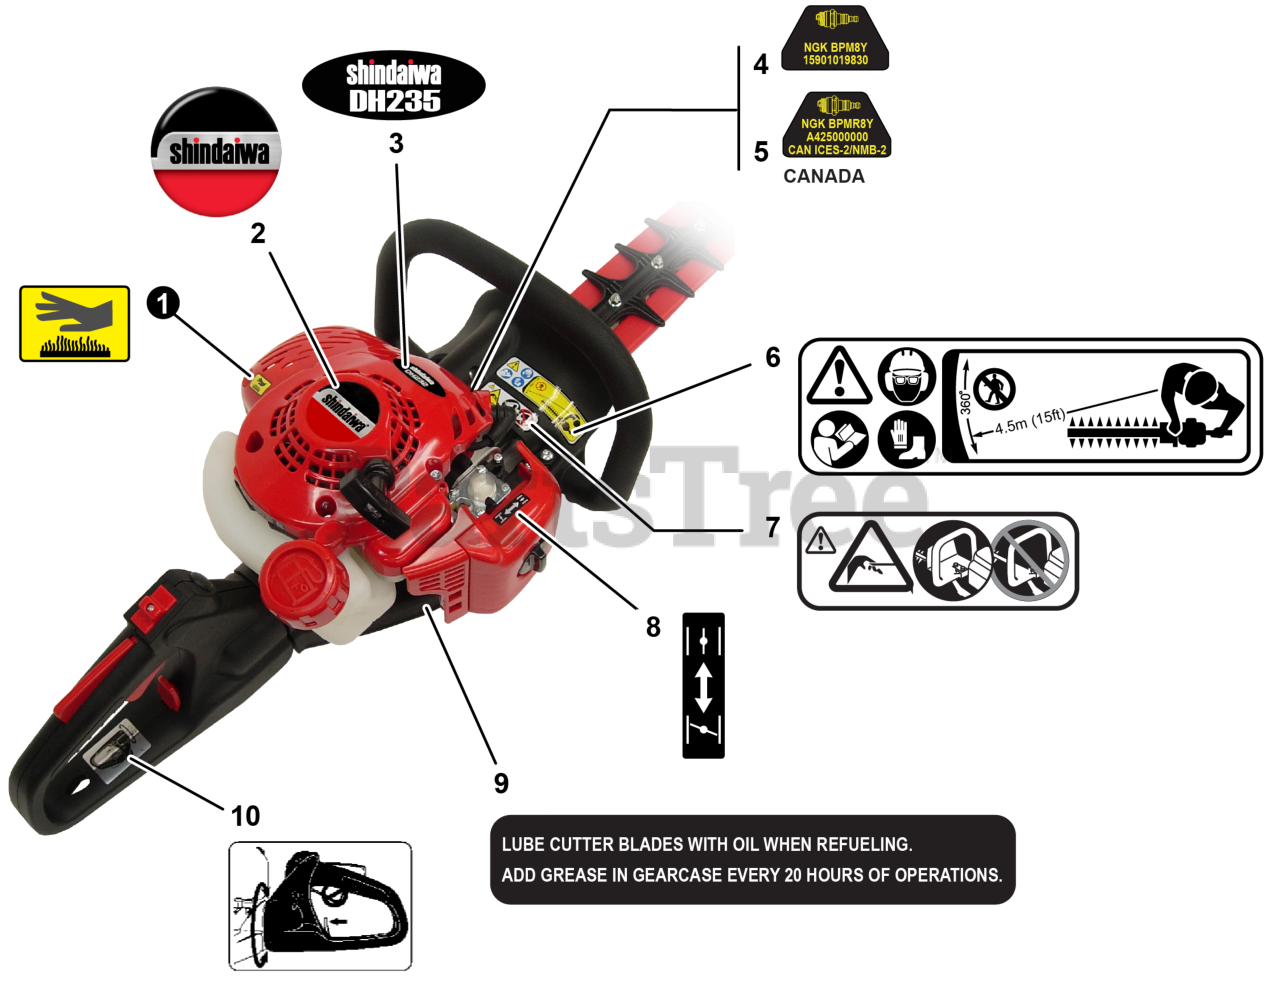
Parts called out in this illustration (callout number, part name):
1	LABEL - CAUTION - HOT
2	LABEL - SHINDAIWA
3	LABEL - MODEL DH235
4	LABEL - SPARK PLUG - BPM8Y
5	LABEL - SPARK PLUG - BPMR8Y
6	LABEL - CAUTION - ISO
7	LABEL - CAUTION
8	LABEL - CHOKE
9	LABEL - LUBE BLADES
10	LABEL - CAUTION
